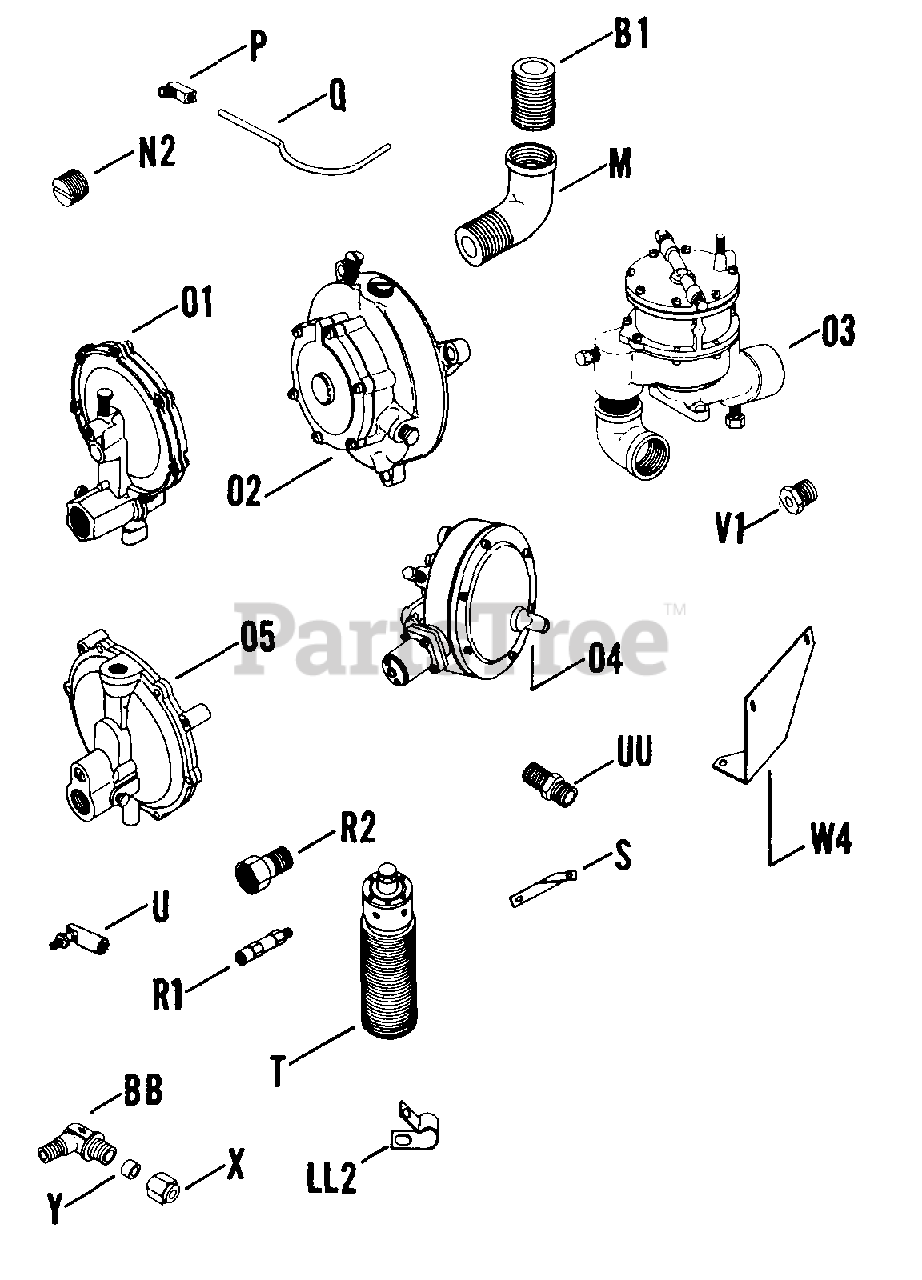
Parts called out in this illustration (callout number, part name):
B1	PIPE - USE 46 136 01
M	ELBOW - USE 47 283 02
X	NUT - (#DSC)
BB	ELBOW - (#DSC)
UU	CONNECTOR
